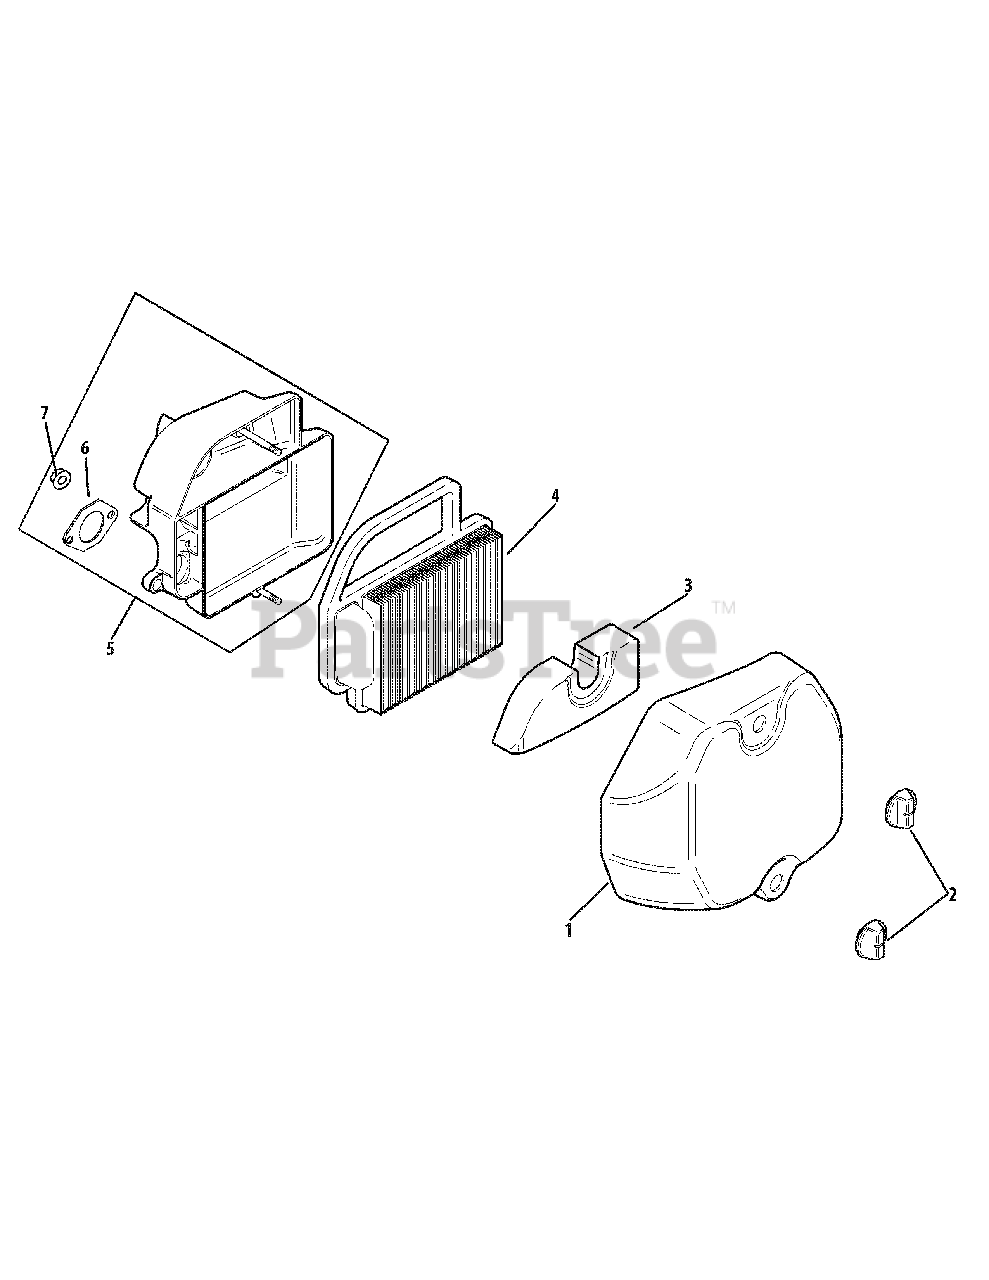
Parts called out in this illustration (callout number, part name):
1	Air Cleaner Cover
3	Pre-Cleaner Element
4	Air Cleaner Element w/Pre-Cleaner
5	Air Cleaner Base Kit (Includes 6)
6	Air Cleaner Base Gasket
7	Hex Flange Nut, M6 x 1.0
